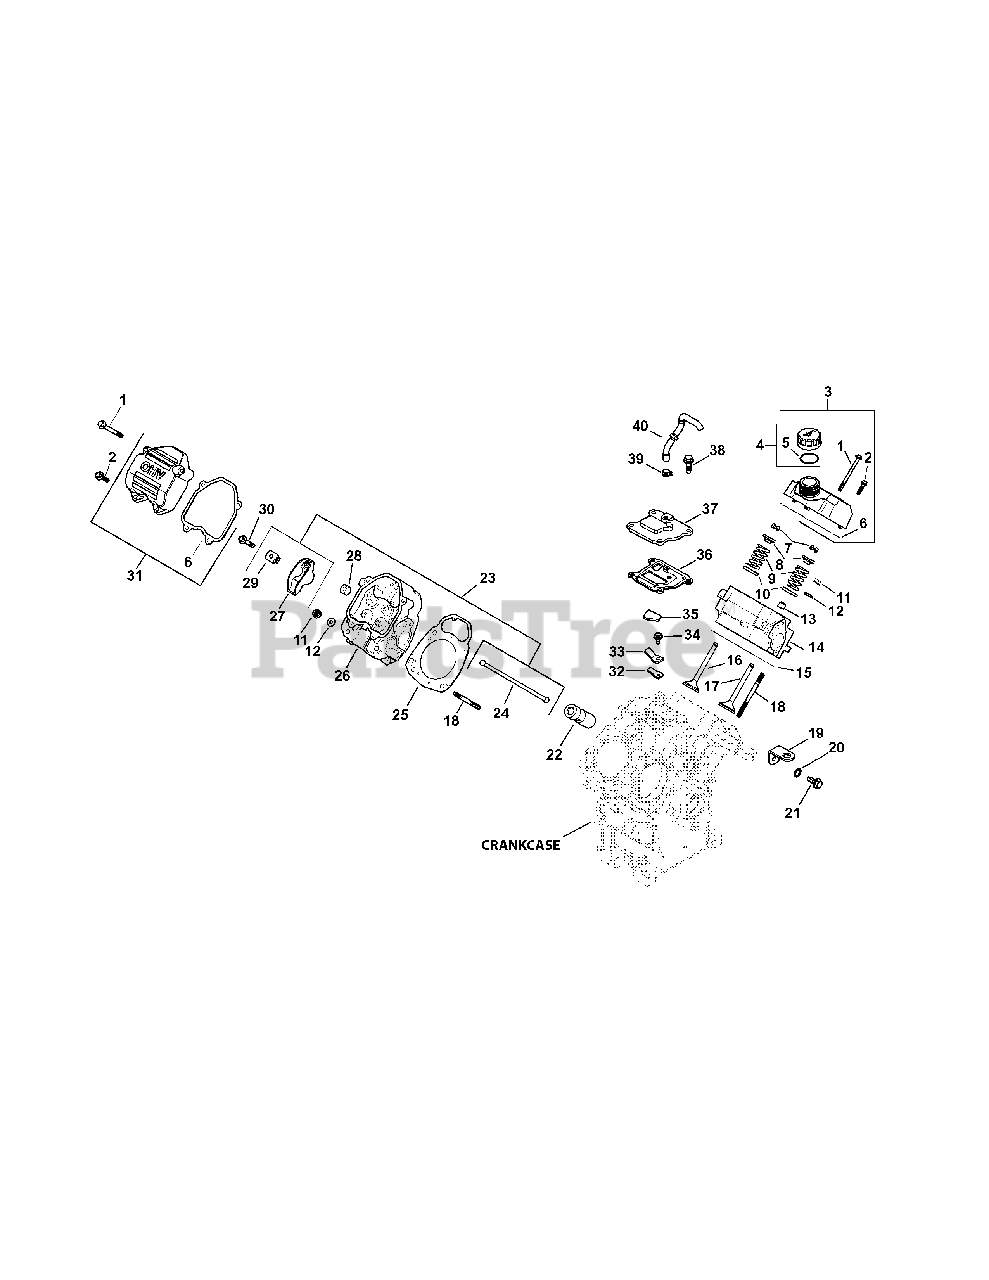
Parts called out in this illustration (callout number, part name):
1	Screw, Flg, M6 x 1.0 x 50
2	Screw, Flg, M6 x 1.0 x 25
3	Kit, Rocker Cover (Oil Fill)
3	Rocker Cover & Gasket (Oil Fill)
4	Kit, Oil Fill Cap (Yellow) (Incl 5)
5	O-Ring, Oil Pick-up
6	Gasket, Valve Cover
7	Kit, Retainer
8	Cap, Valve Spring
9	Spring, Valve
10	Retainer
11	Nut, Flg, M8 x 1.25
12	Washer, Flat, 5/16"
13	Seal, Valve Stem
14	Kit, Cylinder Head (#1 Side)
15	Kit, Cyl Head Gasket (#1 Side)
16	Valve, Exhaust (Std)
16	Valve, Exhaust (.25)
17	Valve, Intake (Std)
17	Valve, Intake (.25)
19	Strap, Lifting
20	Washer, Int Tooth Lock 1/4"
21	Screw, Flg Thd Frm M6x1.0x16
22	Kit, Hyd Vl Lft (Incl 25 357 14-S)
23	Kit, Valve Train (Incl 24, 27, 29)
25	Kit, Cyl Head Gasket (#2 Side)
26	Kit, Cylinder Head (#2 Side)
28	Plug, Pipe Ctsk, 3/8"
29	Pivot, Rocker Arm
30	Screw, Rocker Arm Pivot
31	Kit, Rocker Cover (Includes 6)
32	Reed, Breather
33	Retainer, Reed
34	Screw, Flg Thd Frm, M5x.8x10
35	Filter, Breather
36	Gasket, Breather
37	Cover, Breather
38	Screw, Flg Thd Frm, M6x1.0x20
39	Clamp, Band Spring Hose
40	Hose Assembly, Breather
